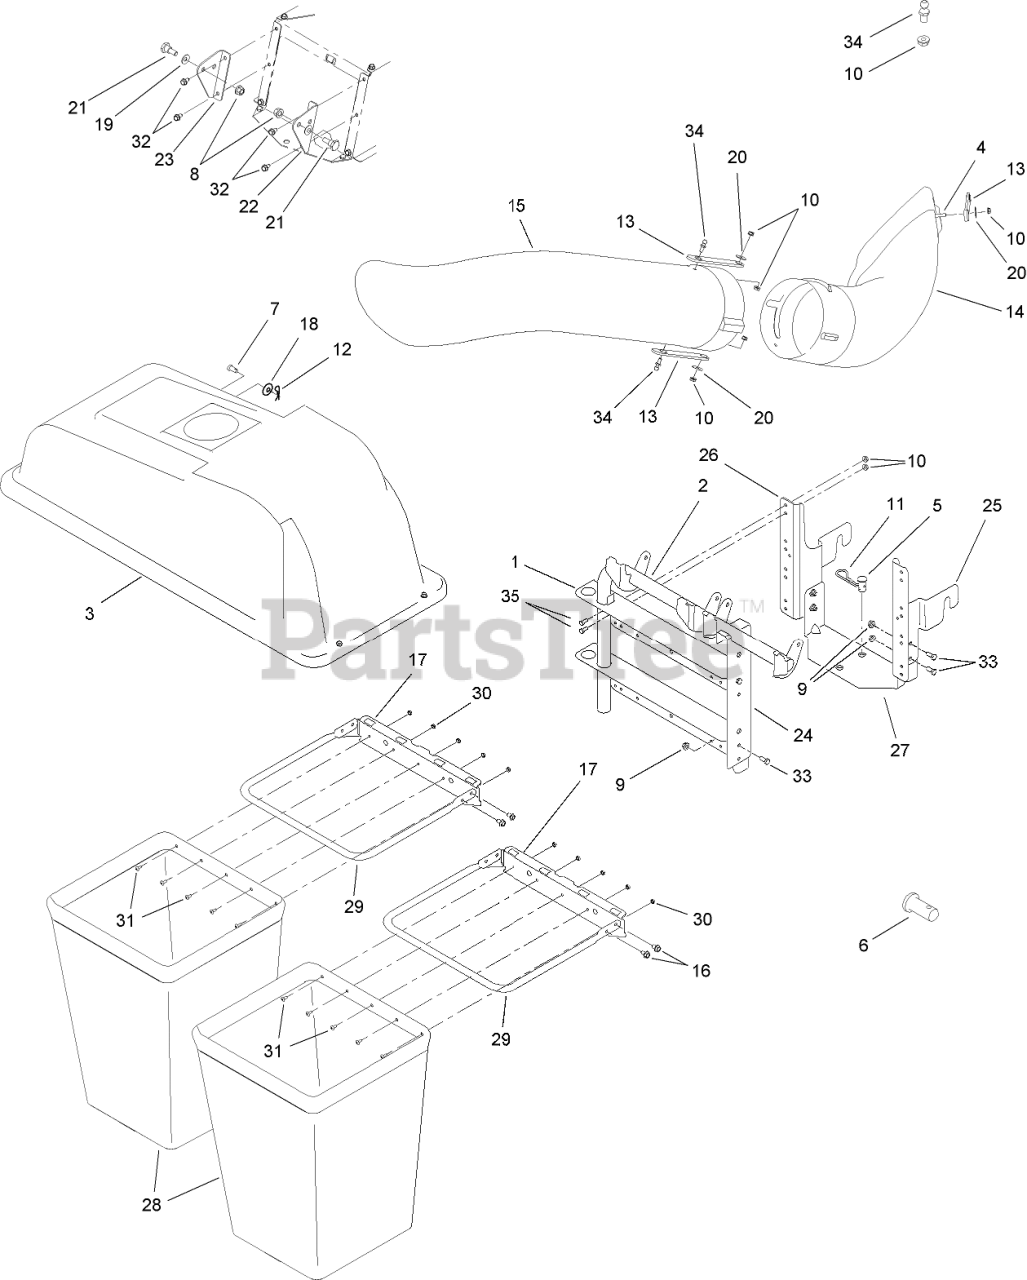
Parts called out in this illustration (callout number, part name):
1	BRACKET-MOUNTING
2	SUPPORT TUBE ASM
3	COVER ASM (DOUBLE)
4	SCREW-HH
5	PIN-CLEVIS
6	PIN-CLEVIS
7	PIN-CLEVIS
8	NUT-LOCK, FLANGE
9	NUT-LOCK, FLANGE
10	NUT-LOCK, FLANGE
11	CLIP-HAIRPIN
12	PIN-CLICK
13	STRAP-CHUTE
14	CHUTE-DISCHARGE
15	TUBE-CHUTE, UPPER
16	SCREW-HWH
17	BRACKET-BAG, HANGER
18	WASHER-BELL
19	WASHER-BELL
20	WASHER-FLAT
21	BOLT-SHOULDER
22	BRACKET-SUPPORT, RH
23	BRACKET-SUPPORT, LH
24	BRACKET-SUPPORT
25	BRACKET-CATCHER, RH
26	BRACKET-CATCHER, LH
27	BRACKET-CROSS, SUPPORT
28	BAG-GRASS
29	FRAME-CATCHER, BAG
30	NUT-SEMS
31	SCREW-TRUSS, MACHINE
32	SCREW-HH, TAP
33	SCREW-HH
34	PIN-CATCHER, GRASS
35	SCREW-HH
